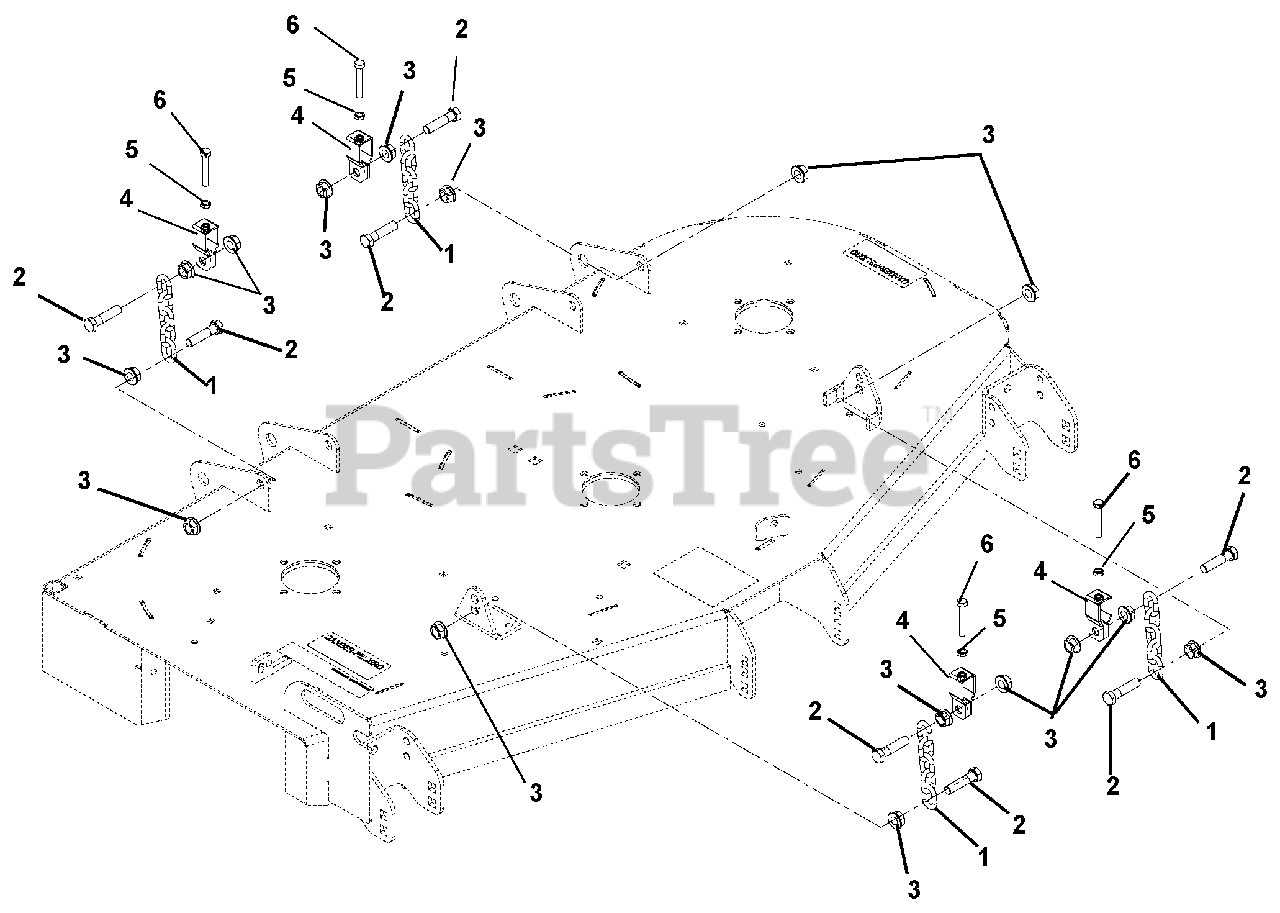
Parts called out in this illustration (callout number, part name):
1	CHAIN, LINK
2	BLT, HEX M12-1.75X50 CLS8.8 YZ
3	NUT-SPNLK-FLG M12-1.75 YZ
4	BRKT, DECK LEVELING
5	NUT- JAM .312-18 YWZC
6	BLT-HEX .312-18X2.00 FTH GR5YZ
